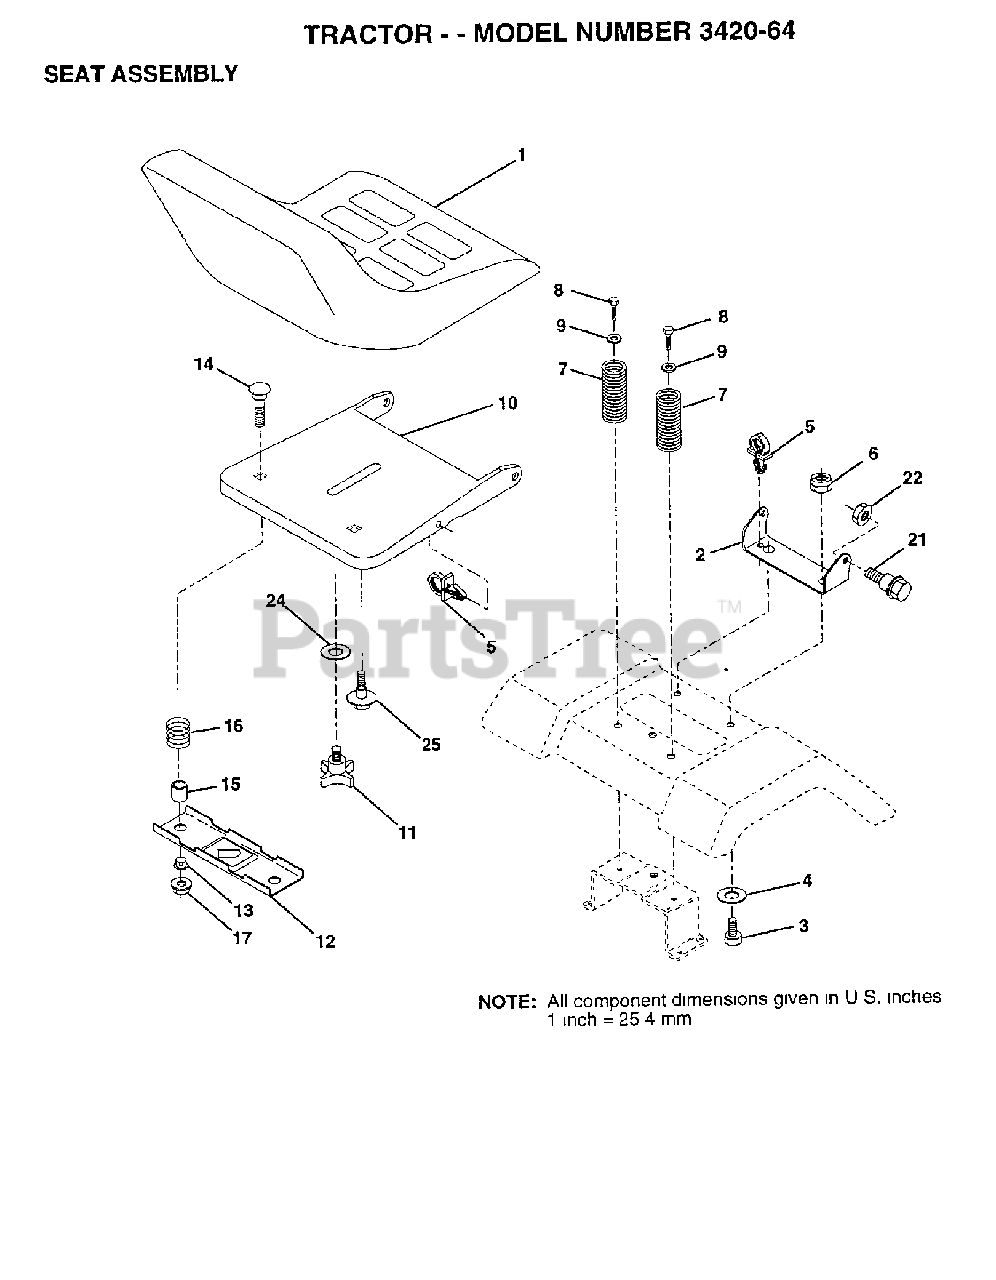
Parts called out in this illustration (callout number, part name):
2	BRKT,SEAT PIVOT**
3	BOLT
4	WASHER PM
5	PUSH CLIP
6	NUT
7	SPRING COMPRESSION
8	SCREW GTV
10	PAN SEAT
12	BRKT SWITCH
14	BOLT CARRIAGE 1/4-20X1 3/8
15	SPACER SPLIT
16	SPRING COMPRESSED
17	NUT T
22	LOCKNUT
25	BOLT, SHOULDER**
